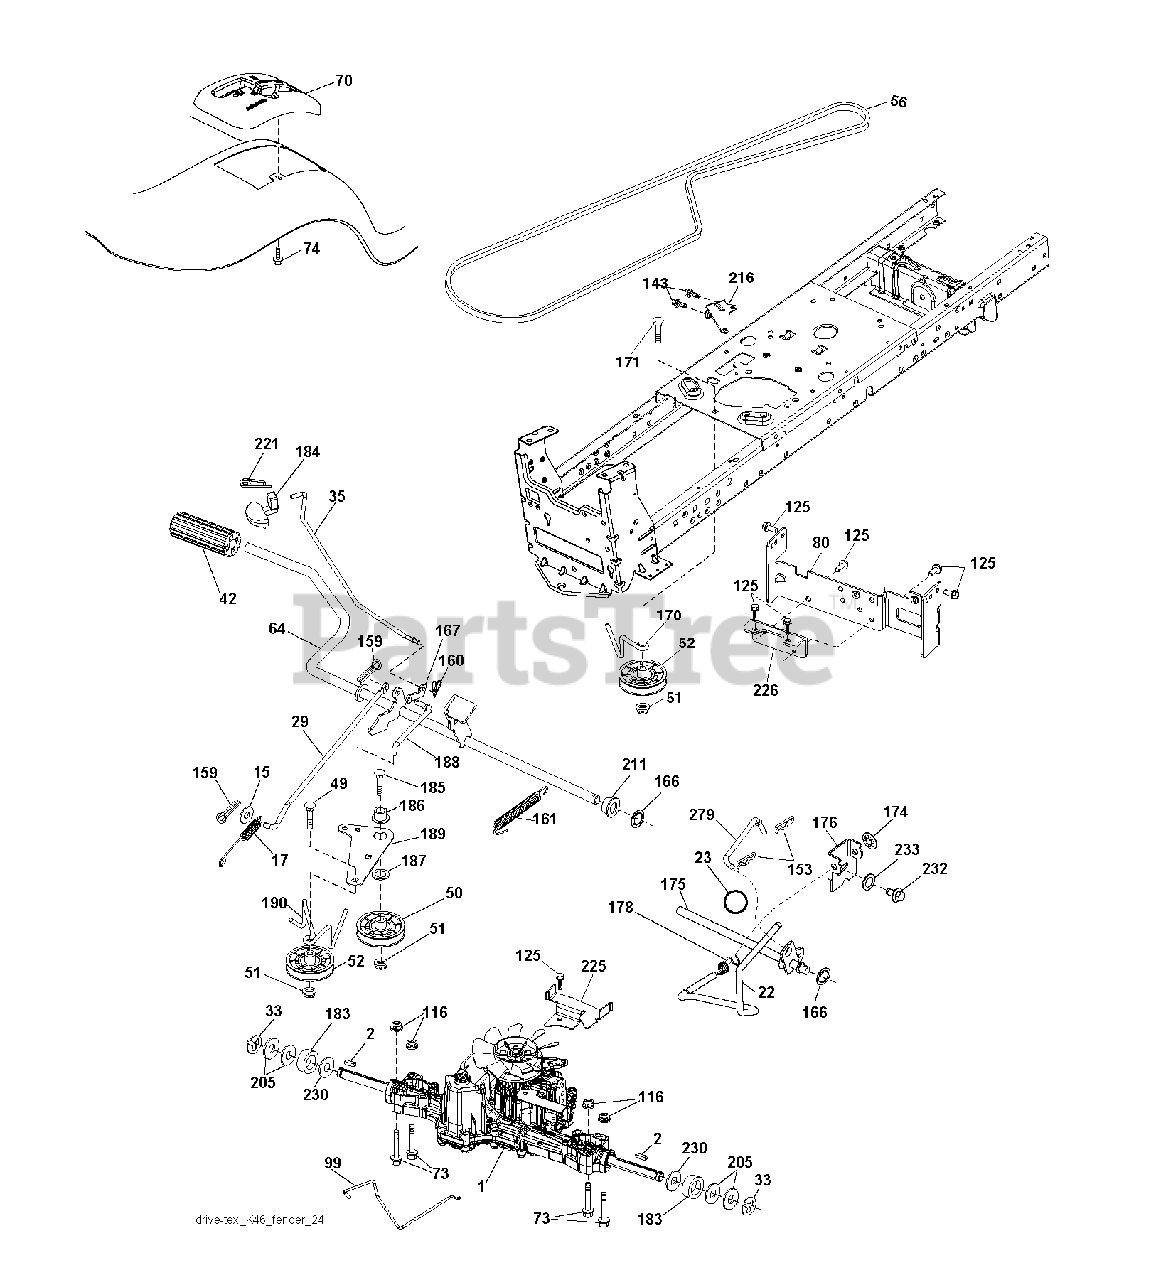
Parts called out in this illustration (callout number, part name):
2	SQUARE KEY
17	SPRING.BRAKE.K46.GREEN
22	ROD.SHIFT.FENDER.TLT.2006
23	PISTOL KNOB
29	ROD.BRAKE.K46
33	E-RING LT
35	ROD.BRAKE.PARKING.LT.T
42	PEDAL COVER T
49	BOLT
50	IDLER.FLAT.910.OFFSET
51	NUT LOCK FLG 3/8-16 UNC
52	IDLER.V-GROOVE.910.OFFSET
64	SHAFT.ASM.PEDAL.BRAKE.
70	CONSOLE.SHIFT.STL.HYD.BLACK
73	BOLT HEX 5/16-18 GR 5
74	SCREW.HI-LO.CONSOLE
80	STRAP TORQUE
99	ROD.SPRING.BYPASS.K46.LT.Z
116	NUT LOCK HEX FLANGE 5/16-18
125	SCREW
153	RETAINER M
159	COTTER PIN
160	RETAINER CLIP
161	SPRING, RETURN LT
166	NUT.PUSH.625
167	LATCH.BRAKE.SPRING
170	KEEPER.V-IDLER.CENTER.
171	BOLT
174	NUT.PUSH.500.2006
175	SHAFT ASM SHIFT
176	ARM.CLEVIS.ROD.SHIFT
178	SPRING.SHIFT.GT2006
183	SPACER AXLE
184	HANDLE.PAKRING.BRAKE.
186	SPACER.RETAINER
187	WASHER 12/32X2X10GA
188	LINK.CLUTCH.GROUND.DRIVE
189	BELLCRANK.GROUND.DRIVE.TEX.
190	KEEPER.BELLCRANK.DRIVE
211	BUSHING.SHAFT.BRAKE.HAND
216	BRACKET.PULLEY.IDLER.W/TEX
221	RETAINER.SPRING.CLIP.H
225	KEEPER.BELT.TRANSAXLE.K46
226	BRACKET.MOUNT.TORQUE.K46.TLT
230	WASHER.HARDENED
232	BOLT FIN HEX 7/16-14 X 1
233	WASHER SERRATED
279	LINK SHIFT
